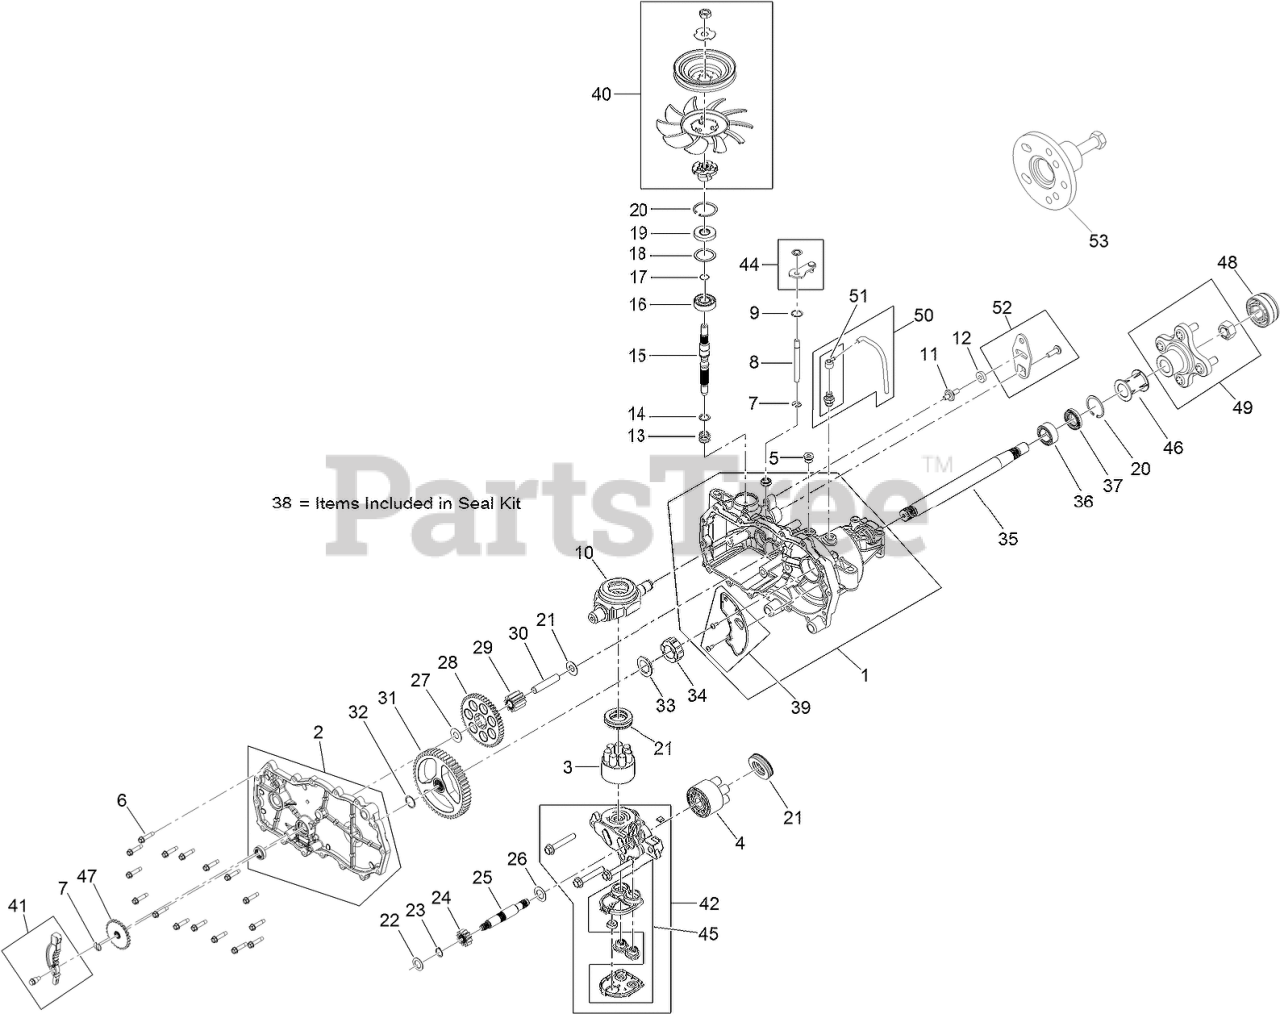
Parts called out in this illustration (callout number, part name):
1	MAIN HOUSING ASM
2	SIDE ASM
3	PUMP BLOCK ASM
4	CYLINDER BLOCK KIT
5	PLUG-THREAD, STRAIGHT
6	SCREW-HHF
7	RING-RETAINING, EXTERNAL
8	ROD-BYPASS
9	RING-RETAINING, INTERNAL
10	SWASHPLATE-TRUNNION
12	PUCK-FRICTION
13	SPRING-BLOCK
14	WASHER-THRUST
15	SHAFT-INPUT
16	BEARING-BALL
17	RING-RETAINING
18	SPACER
19	SEAL-LIP
20	RING-RETAINING
21	BEARING-THRUST
22	WASHER-FLAT
23	RING-RETAINING
24	GEAR-12T
25	SHAFT-MOTOR
26	WASHER
27	WASHER
28	GEAR-49T
29	GEAR-JACKSHAFT, 10T
30	PIN-JACKSHAFT
31	RING-SPIRAL, RETAINING
32	GEAR-52T, BULL
33	WASHER
34	BEARING-SLEEVE
35	SHAFT-AXLE
36	BUSHING-AXLE
37	SEAL-LIP
38	SEAL KIT
39	EXPANSION PLATE KIT
40	FAN PULLEY KIT
41	BRAKE ARM KIT
42	CENTER SECTION FILTER KIT
44	BYPASS KIT
45	FILTER KIT
46	TUBE-AXLE
47	DISC-BRAKE, COG
48	COVER-NUT, AXLE
49	HUB KIT
50	BREATHER KIT
51	BREATHER ASM
52	CONTROL ARM KIT
